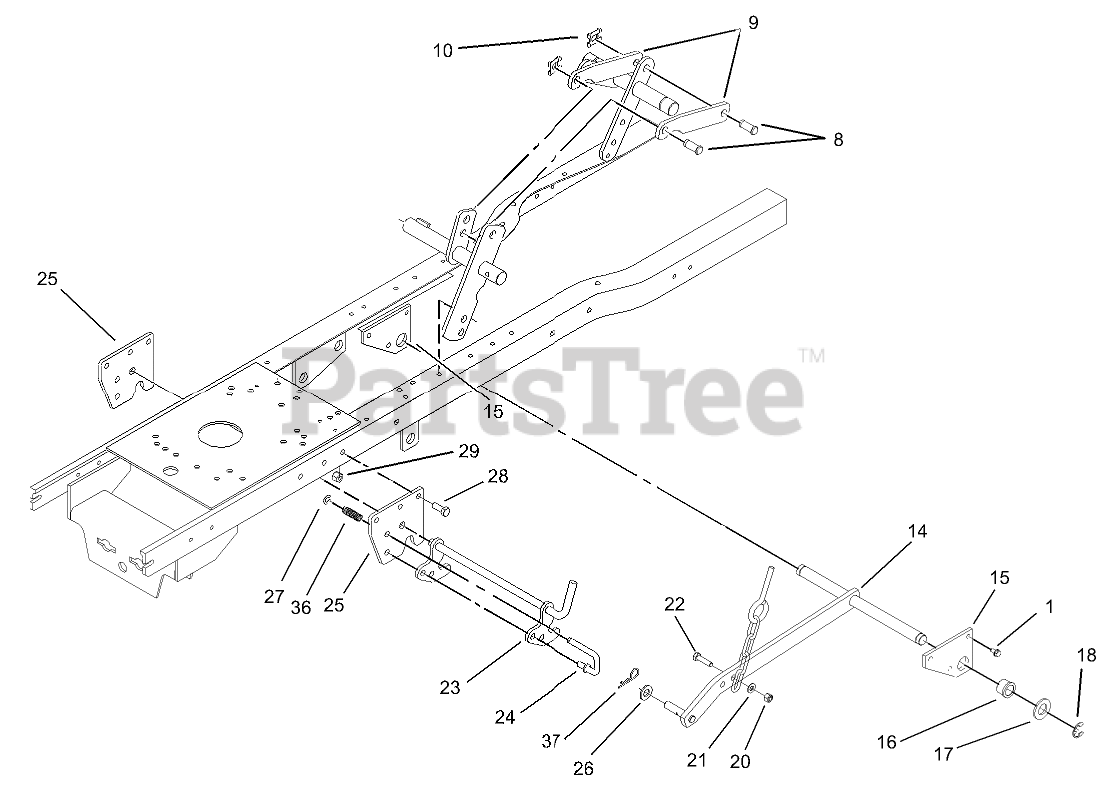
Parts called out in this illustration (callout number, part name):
1	SCREW-HWHTF
8	PIN-CLEVIS
9	STRAP-LINK, LIFT
10	CLIP-PIN
14	LIFT BAR ASM
15	Plate-Lift, Rear
16	BUSHING-FLANGE
17	WASHER-FLAT
18	E-RING
20	NUT-LOCK, NI
21	WASHER-PLAIN
22	SCREW-HH
23	MIDHITCH LATCH ASM
24	ROD-CATCH, MIDHITCH
25	Plate-Hitch
26	WASHER-FLAT
27	RING-RETAINING
28	SCREW-HH
29	NUT-LOCK, NI
36	SPRING
37	PIN-HAIR
